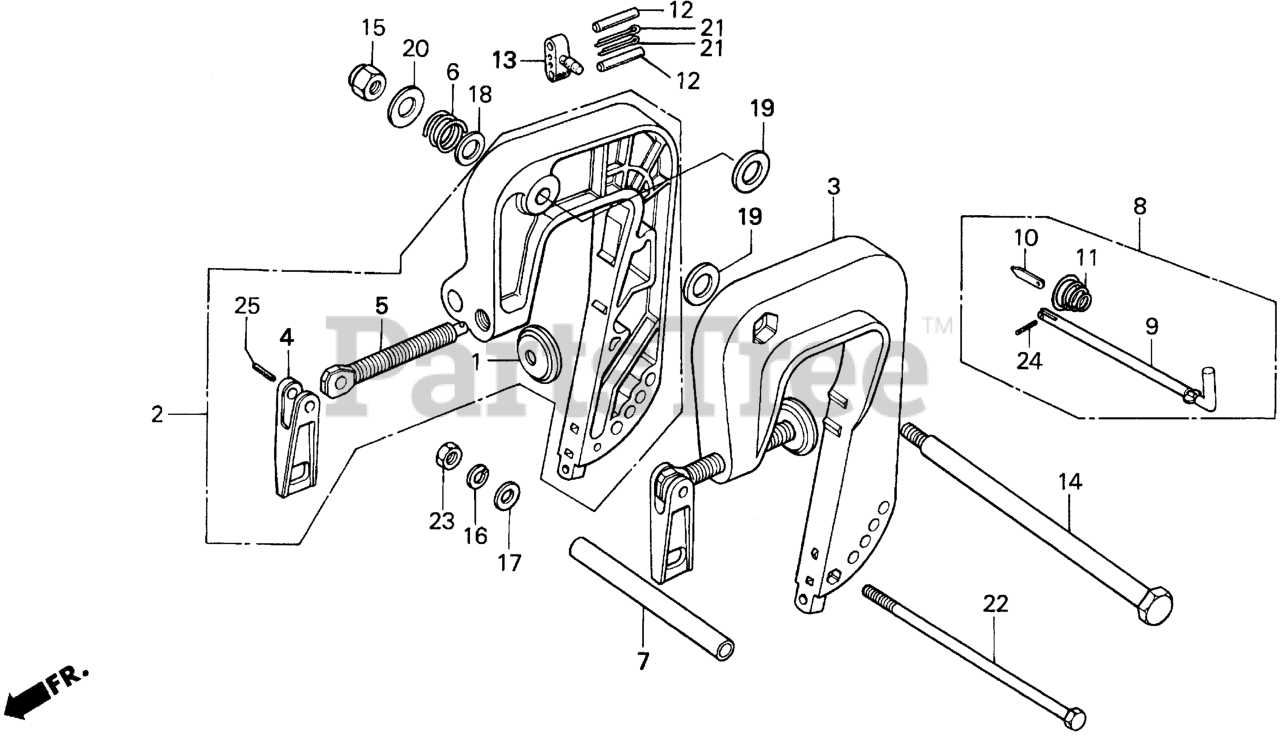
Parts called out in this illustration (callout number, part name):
1	PLATE, PUSH
2	BRACKET, R. STERN *B107* (SENIOR BLUE)
3	BRACKET, L. STERN *B107* (SENIOR BLUE)
4	GRIP, CLAMP *B107* (SENIOR BLUE) (NOT AVAILABLE)
5	SCREW, CLAMP
6	SPRING, TILT (NOT AVAILABLE)
7	COLLAR, DISTANCE (6MM) (NOT AVAILABLE)
8	ROD, ADJUSTING (N/A: SEE COMPONENTS)
9	ROD, ADJUSTING (NOT AVAILABLE)
10	STOPPER, ROD (NOT AVAILABLE)
11	SPRING, ADJUSTING ROD
12	PIN, SHEAR
13	HOLDER, PARTS
14	BOLT, TILTING
15	NUT, SELF-LOCK (8MM) (NOT AVAILABLE)
16	WASHER, SPRING (6MM)
17	WASHER, PLAIN (6MM) Use from Frame SN 4800713.
18	WASHER, PLAIN (10MM)
19	WASHER (10MM)
20	WASHER (8MM)
21	PIN, COTTER (3MM)
22	BOLT, HEX. (6X160)
23	NUT, HEX. (6MM)
24	PIN, SPRING (2X8)
25	PIN, SPRING (4X14)
